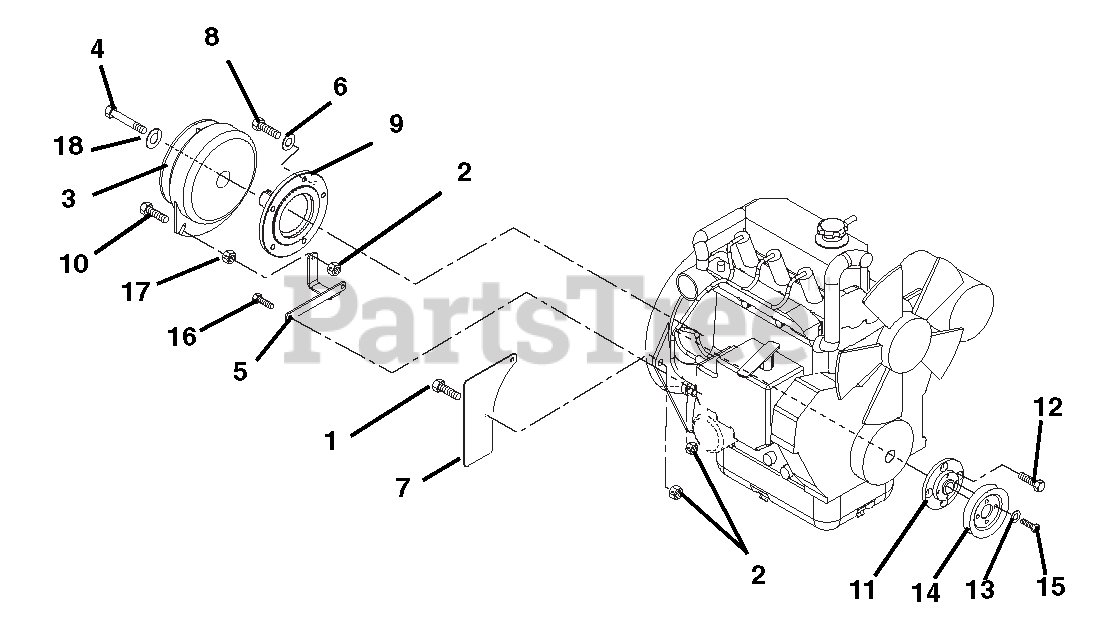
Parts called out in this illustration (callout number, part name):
1	@BLT-HEX .31-18X.75 GR5 YWZC
2	@NUT-LK-TOP-FLG .31-18 YWZC
3	CLUTCH, WARNER 6.323 O/PIN
4	BLT-HEX .44-20X2.50 G5 YZ EP80
5	STABILIZER, CLUTCH
6	@WSHR-LK .31X.078 REG YWZC
7	GUARD, FLYWHEEL
8	BLT, HEX M8-1.25X25 GR8.8YWZC
9	SHAFT, STUB (BRIGGS-DIESEL)
10	@BLT-HEX .31-18X1.50 GR5 YWZC
11	ADAPTER, SHEAVE (DIESEL)
12	BLT, FSCHS M8-1.25X25
13	@WSHR-LK .25X.062 REG YWZC
14	SHEAVE, POLY V 1.000 X 3.25
15	@BLT-HEX .25-20X.75 GR5 YWZC
16	@BLT-HEX .31-18X1.00 GR5 YWZC
17	@NUT-HEX .31-18 YWZC
18	@WSHR-LK .44X.109 REG YWZC
NS	KIT,BRAKE POLE MODULE REPLACE
